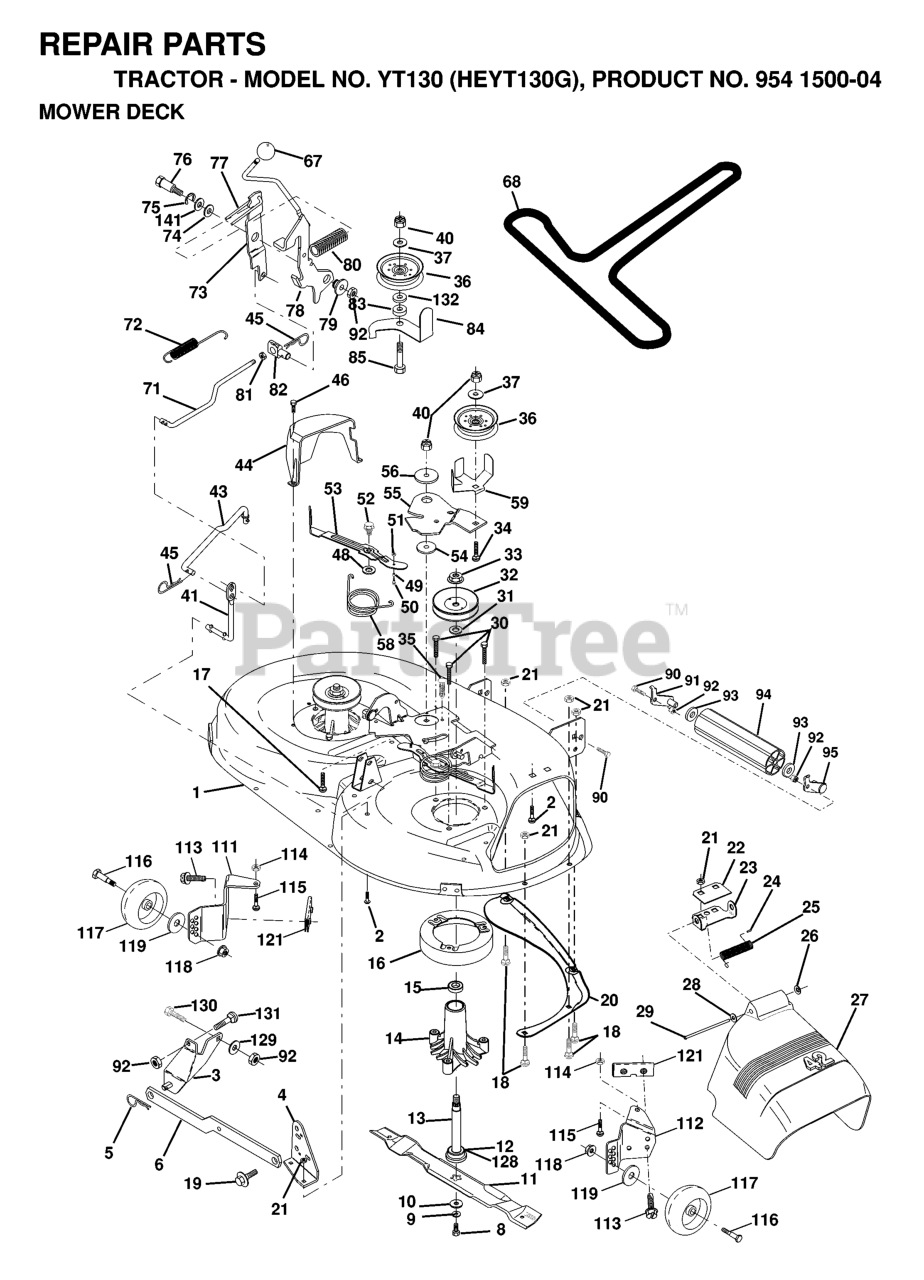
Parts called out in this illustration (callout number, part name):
1	DECK 42"
2	RP BOLT 5/16-18 X3/4 ZN/YEL GR
3	BRKT ASM SWAY BAR
4	BRKT DECK SW BAR
5	RETAINER-SPRNG RB
6	REAR SUSP ARM
8	BLADE BOLT
9	LOCKWASHER
10	WASHER.BLADE
11	BLADE 42", YTH 160
12	BEARING.BALL.#6204.(MANDREL)
13	SHAFT ASM VENT
14	HOUSING.MANDREL.VENTED (MACHD)
16	STRIPPER
17	BOLT
18	BOLT
19	BOLT SHD 5/16-18
20	BAFFLE
21	LOCKNUT
22	STIFFENER BRACKET
23	DEFLECTOR BRACKET
24	CAP-SLEEVE LT
25	SPRING TORSION
26	NUT PUSH M
27	SHIELD.DEFLECTOR.MOWER.42".BLK
28	Washer 11/32 x 5/8 x 16 Ga SD
29	ROD.HINGE
30	SCREW
31	WASHER
32	PULLEY/MANDREL
33	NUT
35	FASTENER.XMAS.TREE
36	FLAT IDLER PULLEY
37	WASHER
43	CLUTCH ROD
44	GUARD MANDREL LH BLACK
45	RETAINER M
46	SCREW.1/4-20X5/8
49	ROLLER ASSY
52	BOLT.SHOULDER.5/16-18
53	ARM ASM PAD BRAD
54	HARDENED WASHER
55	ARM IDLER 42" MOWER LT/YT
56	SPACER RETAINER
59	GUARD, BELT
67	KNOB.CONTROL.7/16
71	CLUTCH ROD
72	RETURN SPRING
73	ARM CLUTCH SECONDARY
77	KEEPER SPRING
78	CLUTCH LEVER ASSY
79	BUSHING.FLANGE.E-RING.GROOVE
80	SPRING-CLUTCH (2 2 PW01)
81	NUT
82	TRUNNION.ADJUSTABLE.3/8-16
84	KEEPER.BELT.IDLER
85	BOLT
90	BOLT
91	BRACKET LH (A)
92	NUT
93	Washer 1 17/32 X 7/8 X 16 Ga
94	NOSE ROLLER
95	BRACKET RH (B)
111	BRACKET WHEEL GAUGE LH 42" DK
112	BRACKET WHEEL GAUGE RH 42" DK
113	SCREW.THDROL.5/16-18X3/4.TTY
114	NUT
115	BOLT.CARR.5/16-18X1/2
116	BOLT, SHOULDER
117	WHEEL GAGE DONUT
118	LOCKNUT
119	WASHER.5/16.FLAT.STE.STD.
121	BRACKET.EXTRUDED.GAGE.WHEEL
128	WASHER FELT
129	WASHER
131	BOLT D
132	Washer 13/32 x 1-3/8 x 13 Ga.
141	THRUST WASHER
